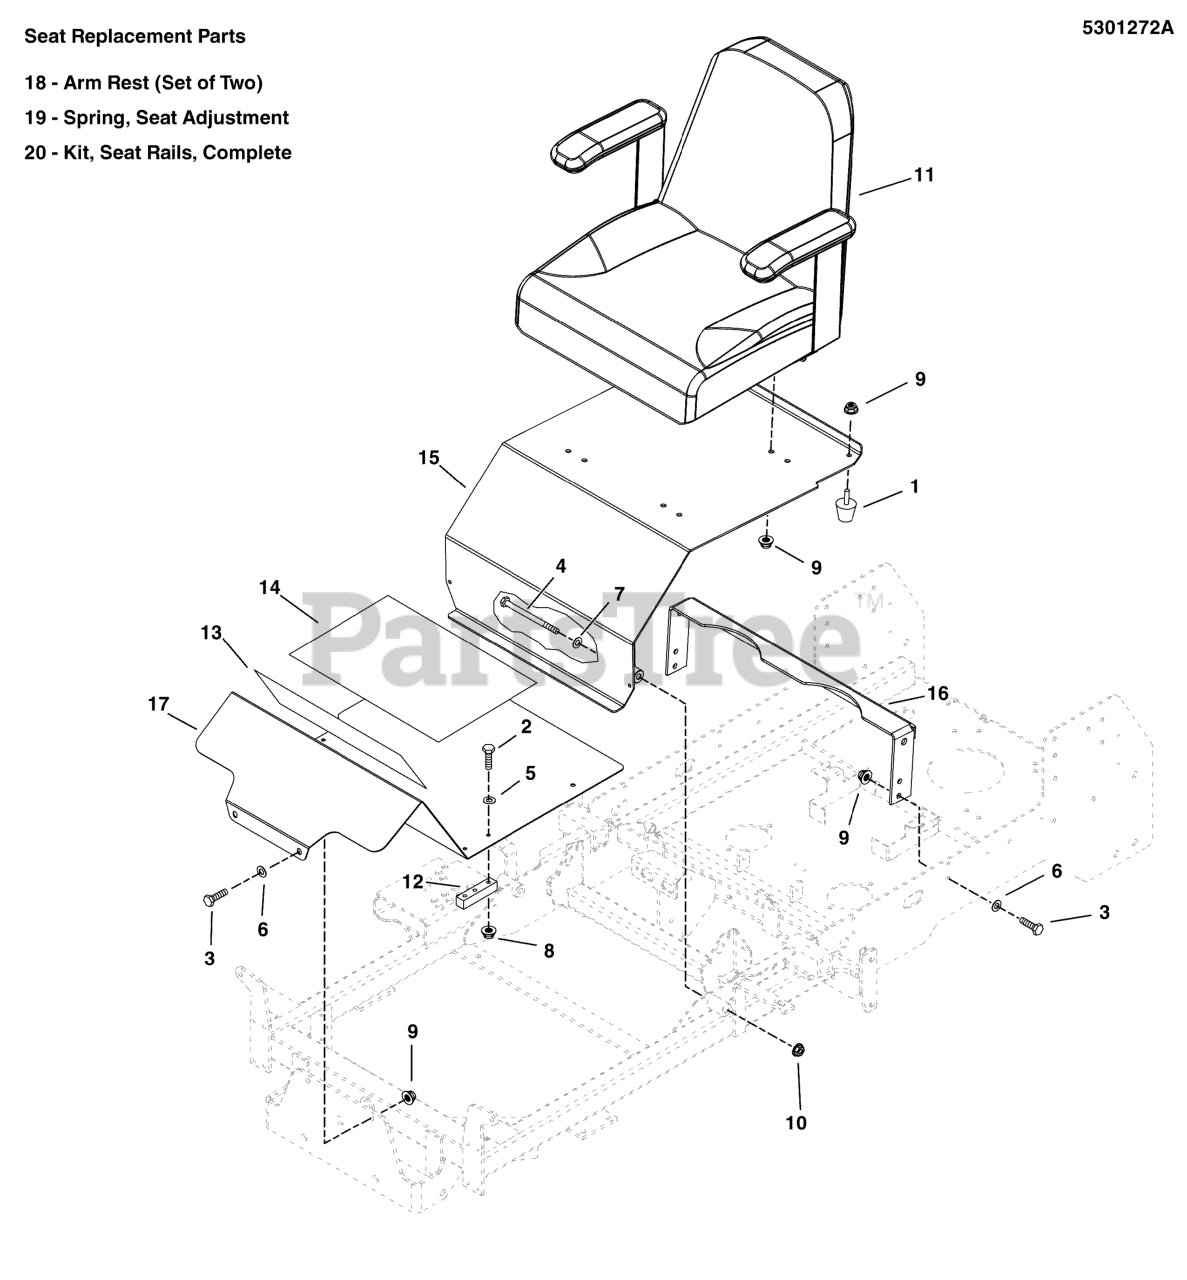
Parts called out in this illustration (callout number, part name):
1	BUMPER, RUBBER 5/16-18
2	BOLT, 1/4-20 X 1-1/4, GD5
3	BOLT, 5/16-18 X 1 GD5 YZ
4	BOLT, 3/8-16 X 6" GD5 CZ
5	WASHER, 1/4 SAE
6	WASHER, 5/16" SAE
7	WASHER, 3/8 SAE
8	NUT, 1/4-20 HEX NYLOCK FLANGE
9	NUT, 5/16-18 HEX NYLOCK FLANGE
10	NUT, 3/8-16 HEX NYLOCK FLANGE
11	SEAT, XB-180, NO LOGO, BLACK
12	BLOCK, DECK LIFT SUPPORT
13	SAFETY WALK, 17.13 X 6.00
14	SAFETY WALK, 17.13 X 11.50
15	WELD, SEAT PLATE - RED
17	PLATE, FLOOR - RED
19	SPRING, EXTENSION, SEAT ADJUSTMENT (BLK OR SLVR)
